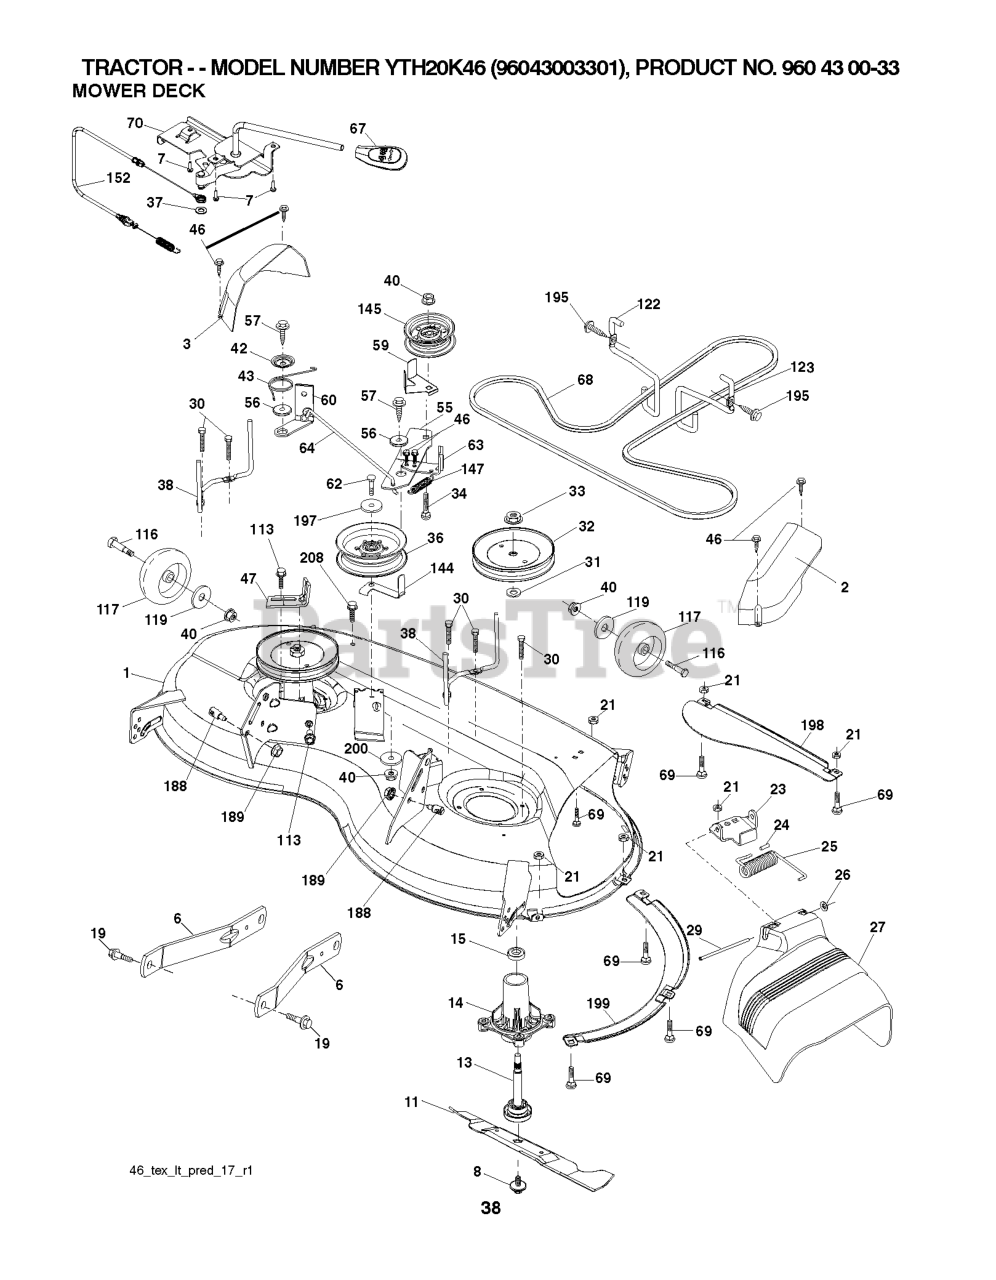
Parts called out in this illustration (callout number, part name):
1	DECK.WELDMENT.46"
2	COVER.MANDREL.RH.46"
3	COVER.MANDREL.LH.46"
6	ARM.SUSPENSION.MOWER.R
7	SCREW.#10 X 0.750.BOS
8	BOLT.WASHER.ASM.7/16-2
11	BLADE.MOWER.46".HI.LIFT
13	SHAFT.ASM.MDRL.N/GREASE.38
14	RP.HOUSING.MANDREL.4PT.
19	BOLT.SHOULDER
21	LOCKNUT
23	BRKT.DEFLECTOR.38"2005+
24	CAP-SLEEVE LT
25	SPRING.TORSION.DEFLECT
26	NUT PUSH M
27	SHIELD.DEFLECTOR.MOWER.46"BLAC
29	ROD.HINGE
30	SCREW, WASHER HEAD
31	WASHER.SPACER.MANDREL
32	PULLEY.MANDREL.5.438.PD
33	NUT.FLANGE.LOCK.TOP
34	BOLT.3/8-16X1.50
36	PULLEY.IDLER.2006
37	WASHER
38	KEEPER.BELT.LH.MANDREL
40	NUT LOCK FLG 3/8-16 UNC
42	SPRING.TORSION.BRAKE
43	SRPING.TORSION.RETAINE
46	SCREW.1/4-20X5/8
47	BRKT.CLUTCH.CABLE
56	SPACER.RETAINER
57	SCREW 3/8-16X1
59	GUARD, BELT
60	ARM BRAKE MOWER RH 38"
62	BOLT-HEX EAK
63	ARM.BRAKE.ZINC
64	LINKAGE.ASM.BRAKE.CLEAR.ZINC
67	HANDLE.CLUTCH.CABLE.LT
68	V-BELT
69	BOLT
70	CLUTCH.ASM.CABLE.HUSQ.TEX
113	BOLT.5/16HEX.WHS.HD
116	BOLT.SHOULDER.3/8-16X3-5/8.
117	RP WHEEL. GUAGE RALLY
119	WASHER
122	KEEPER BELT ENGINE LH
123	KEEPER BELT RH
144	KEEPER.BELT.MOWER
145	PULLEY.IDLER.48"PRIMARY
147	SPRING RETURN
152	CABLE CLUTCH MANUAL W/SPR.
188	STUD.FASTNER.W/ANTI-ROTATE
189	NUT LOCK HEX FLANGE 5/16-18
195	SCREW, 3/8-16X3/4
197	WASHER
198	BAFFLE CENTER FRONT
199	BAFFLE FRONT RH
200	WASHER.13/32 X 1 X 1/2.11GUARD
208	SCREW 3/8-16X1/2
